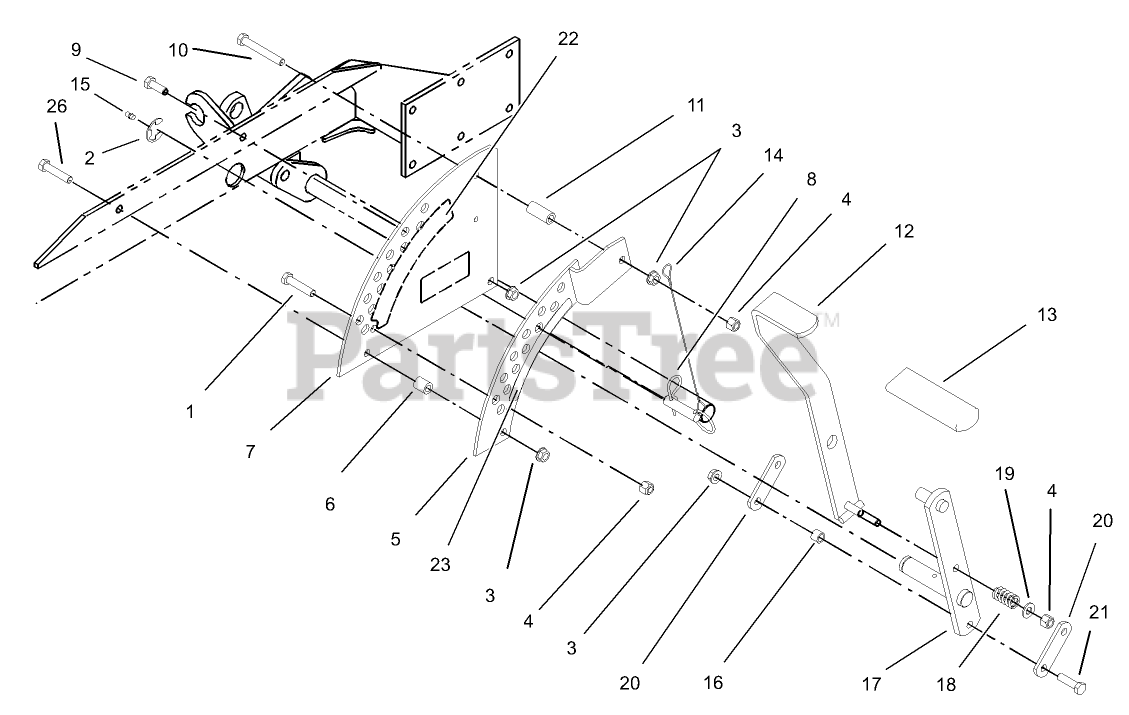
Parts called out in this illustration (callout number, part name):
1	SCREW-HH
2	RING-RETAINING, EXT
3	NUT-HHF, WHIZ
4	NUT-LOCK, NI
5	PLATE-LIFT, DECK
6	BUSHING-LEVER, LIFT
7	PLATE-LIFT, DECK
8	PIN-COTTER
9	SCREW-HH
10	SCREW-HH
11	BUSHING-LEVER, LIFT
12	HANDLE-LIFT
13	GRIP-LEVER, LIFT
14	PIN-HITCH (W/LANYARD)
15	FITTING-GREASE
16	Bushing
17	LIFT ARM ASM
18	SPRING-COMPRESSION
19	WASHER-FLAT
20	ARM-LIFT, DECK
21	SCREW-HH
22	DECAL-DECK HEIGHT, OUTER
23	DECAL-DECK HEIGHT, INNER
26	SCREW-HH
